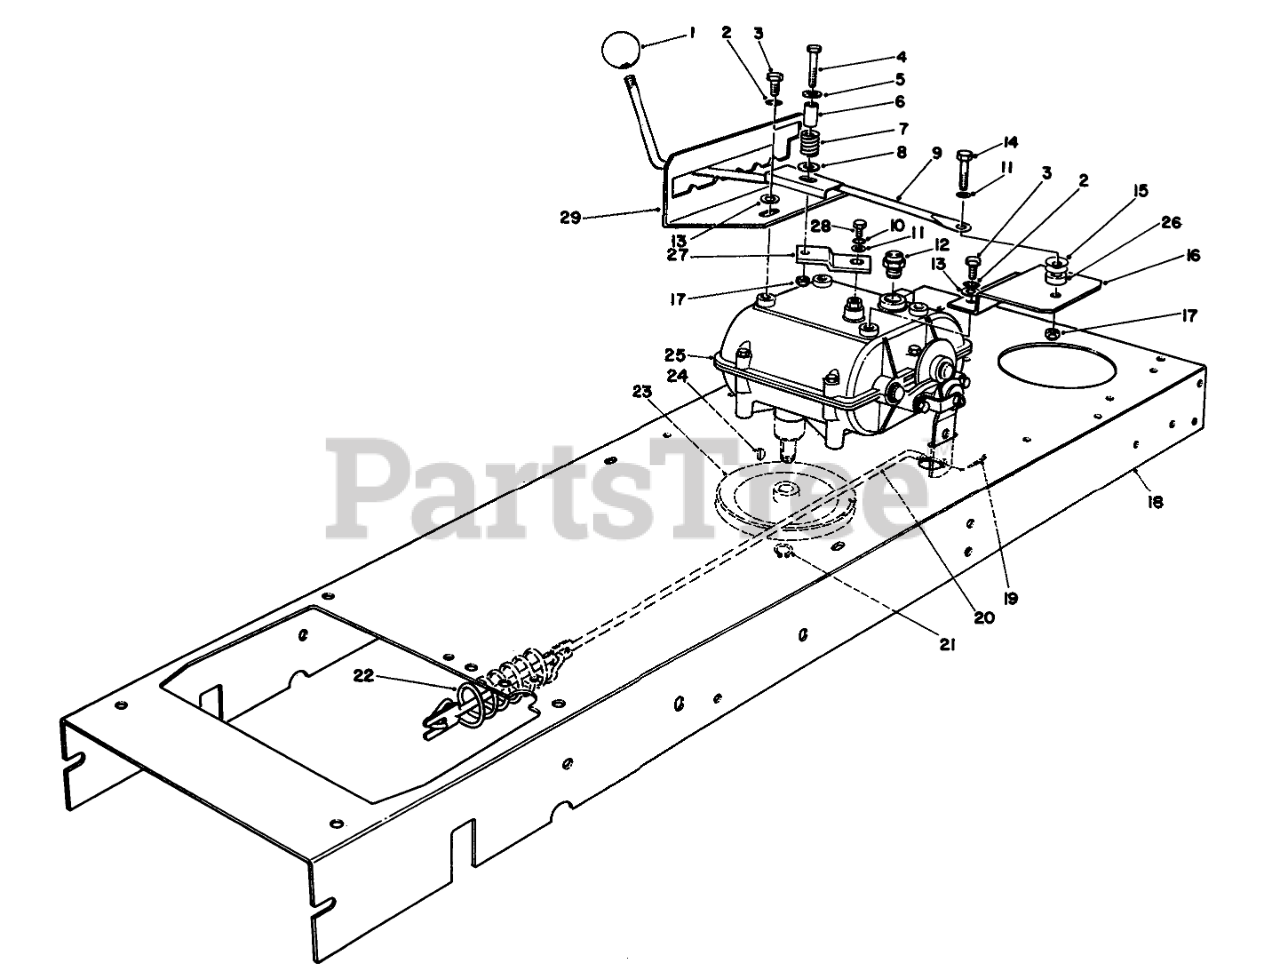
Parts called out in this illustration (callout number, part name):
2	WASHER-LOCK
3	SCREW-HWHTF
4	SCREW-HH
5	WASHER-FLAT
6	SPACER-SPLIT
7	SPRING-COMPRESSION
8	WASHER-FLAT
9	Lever-Shift
10	WASHER-LOCK
11	WASHER-FLAT
12	NEUTRAL SWITCH
13	WASHER-PLAIN
14	SCREW-HH
15	PUSH IN NUT
16	BRKT - SHIFTER MTG B
17	NUT-LOCK, NI
18	Frame-Main
19	Pin-Cotter
20	BRAKE ROD
21	RING-SNAP, EXTERNAL
22	SPRING-EXT
23	PULLEY
24	KEY-WOODRUFF
25	TRANSMISSION
26	SPACER-PIVOT
27	LEVER-SHIFT
28	SCREW-HH
29	Gate-Shift
